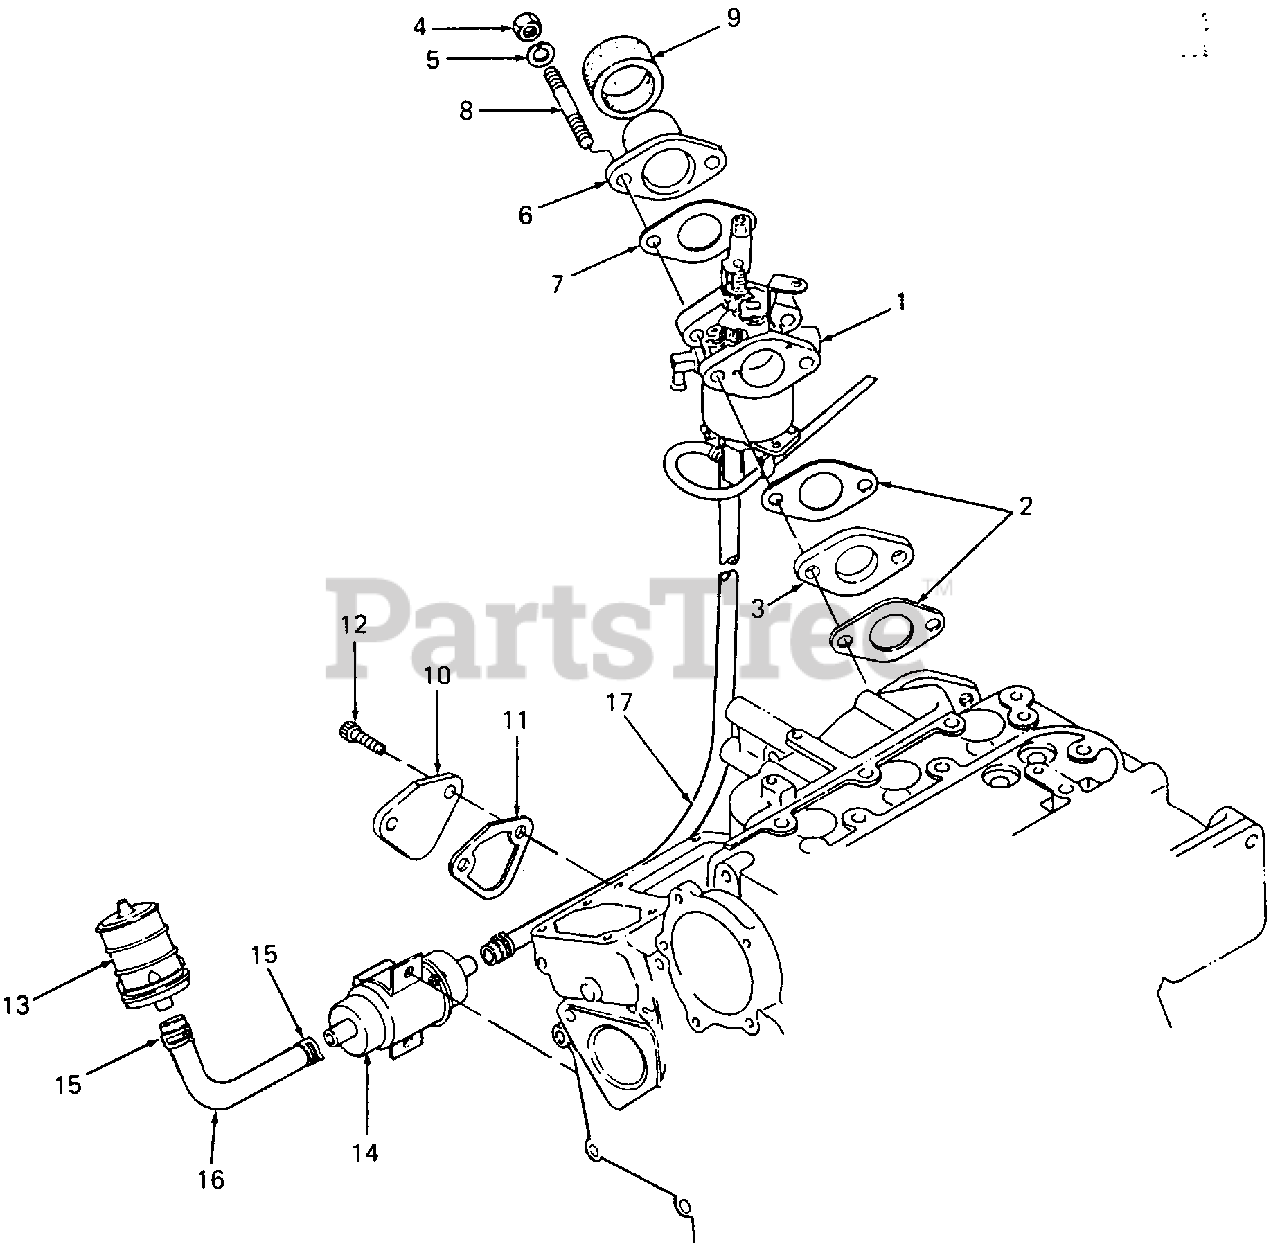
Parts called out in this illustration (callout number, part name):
1	Carburetor Assy
2	Gasket, Carburetor
3	Flange, Carburetor
5	Washer, Spring
6	Flange, Air Cleaner
7	Gasket, Air Cleaner
13	Fuel Filter Assy
14	Fuel Pump Assy
15	Clamp, Hose
16	Line, Fuel -2" Lg
17	Line, Fuel -12" Lg
